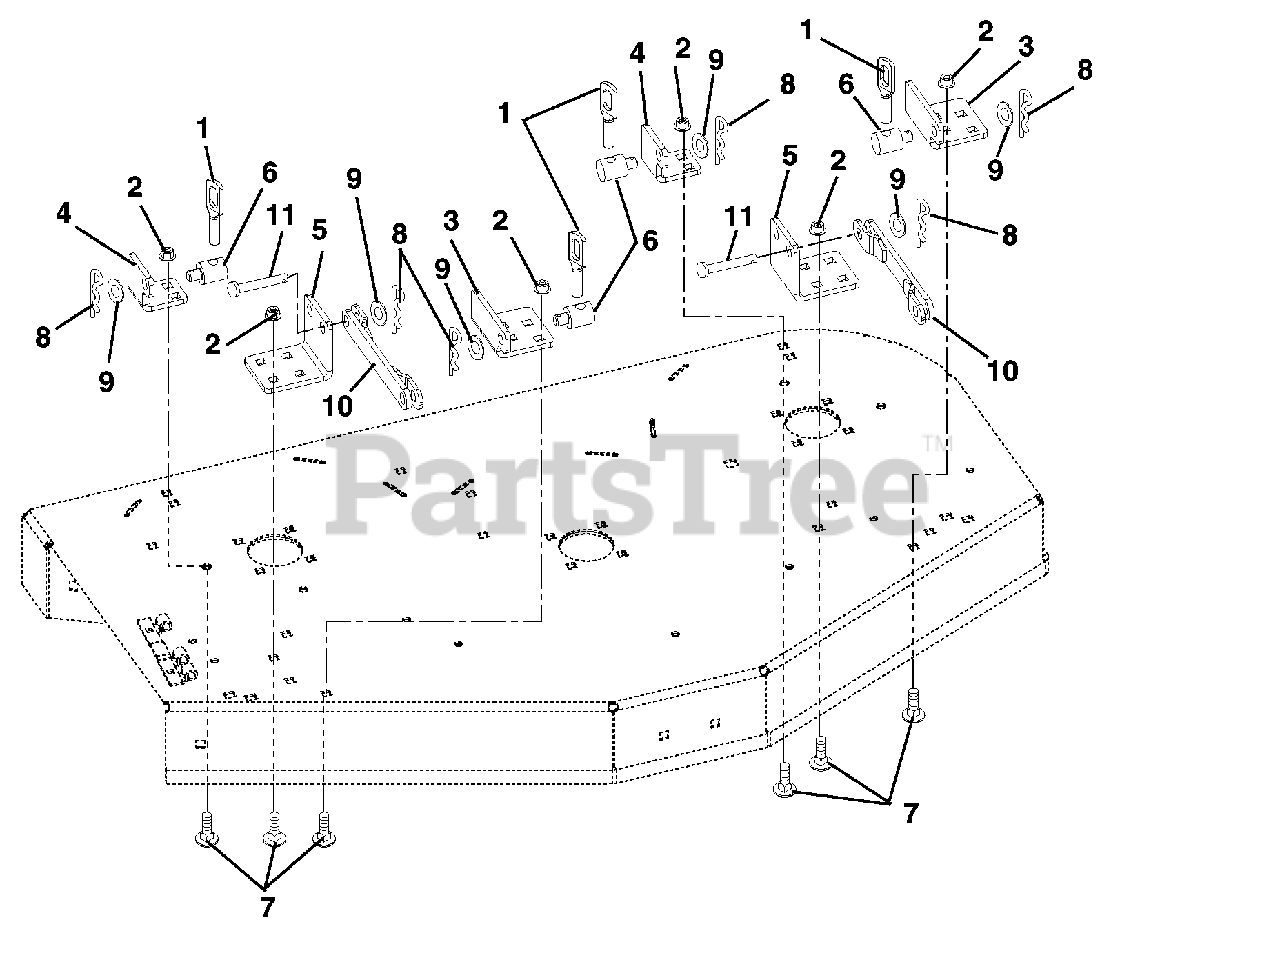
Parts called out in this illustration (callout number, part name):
1	DECK LINK
2	@NUT-LK-NYL-FLG .38-16 YWZC
3	BRACKET, MOUNT,FRONT
4	BRACKET, REAR MOUNT
5	BRACKET, STABILIZER
6	TRUNNION-.50
7	@BLT-RDHDSQNK .38-16X1.00 G5YZ
8	PIN, HAIR, EXT - #16 YWZC
9	WSHR-FL-STL.511X1.441X.125 YWZ
10	WMT, STABILIZER ARM
11	PIN-CLEV .494X1.25 YWZC
